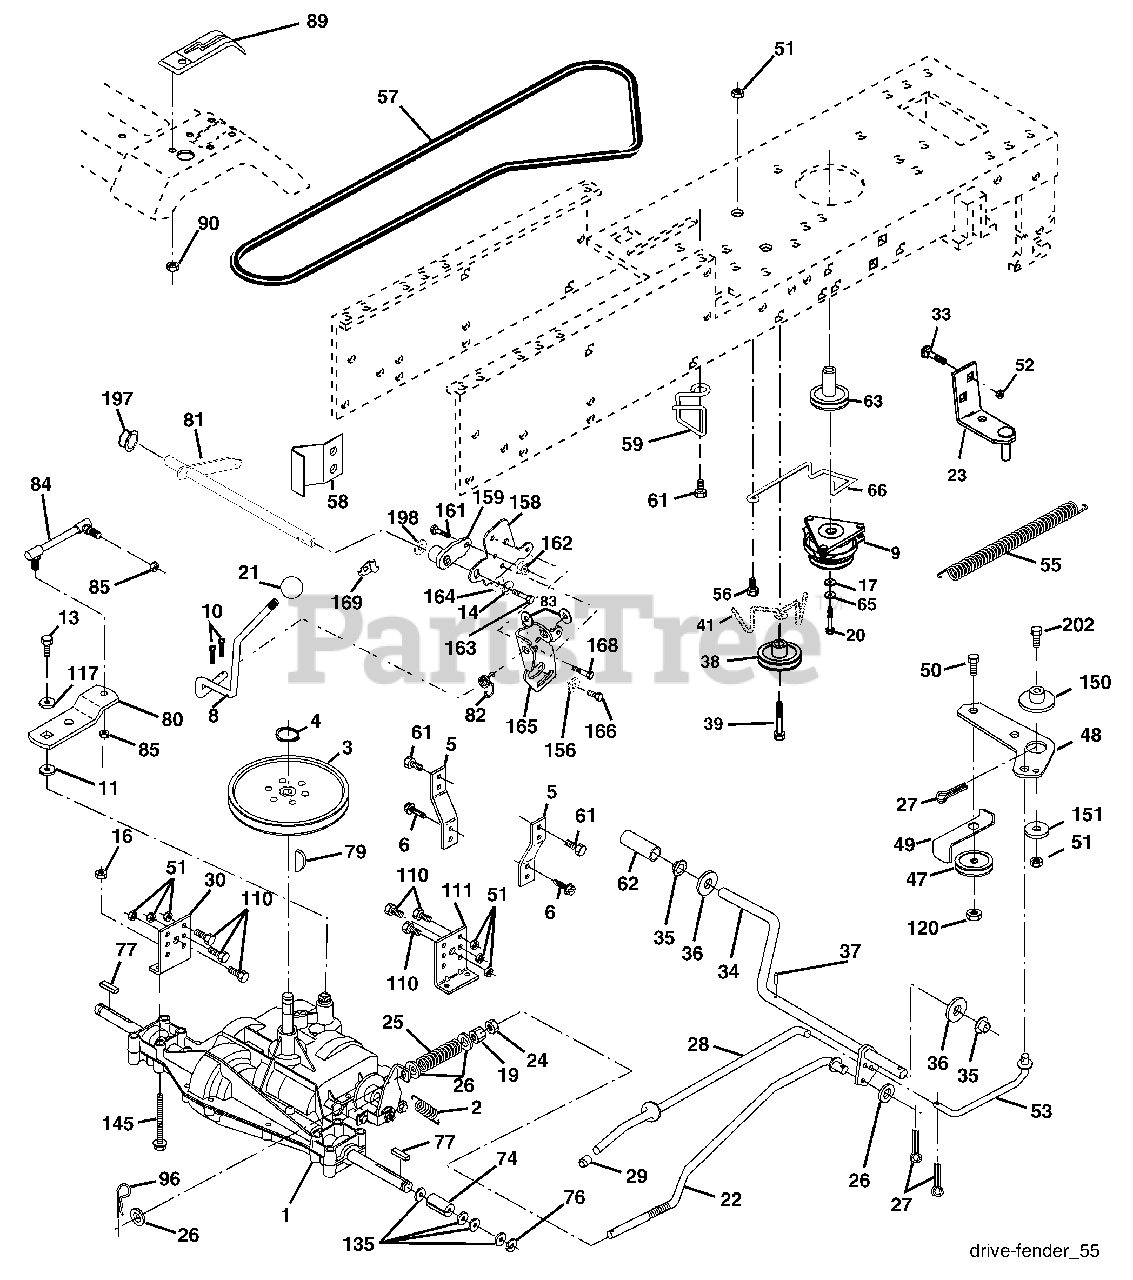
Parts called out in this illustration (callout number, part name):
2	Spring Brake Return
3	Pulley Transaxle
4	Ring Retainer
5	Strap Torque
6	Screw 5/16-18 x 3/4
8	Rod Shift Fender Adjust Yt
9	Clutch Ogura
10	Pin, Cotter 1/8 x 1
11	Washer Plate
13	Bolt 1/4-28
14	Washer Lock Hvy Helical
16	Nut Lock Hx w/Ins. 5/16-18 Unc
17	Washer 1-1/2 x 15/32 x .250
19	Nut, Lock Hex w/Ins. 3/8-16 Unc
20	Bolt 7/16-20 x 4 Gr. 5-1.5
21	Knob
23	Bracket Anti Rotation
24	Nut, Hex Jam 3/8-16
25	Spring, Rod, Brake
26	Washer 13/32 x 5/8 x 16 Ga.
27	Pin, Cotter 1/8 x 3/4
28	Rod, Brake, Park
29	Cap, Brake Parking Black
30	Bracket, Transaxle, L.H.
33	Bolt 3/8-16 x 1
34	Shaft, Foot Pedal
35	Bearing Nylon
36	Washer 21/32 x 1 x 16 Gauge
37	Pin,Roll 3/16 x 1
38	Pulley Idler Composite
39	Bolt Rdhd 3/8-16 Unc x 3
41	Keeper, Idler
47	Pulley, Idler
48	Bellcrank Clutch Grnd Drv Stl
49	Retainer, Belt
50	Bolt 3/8-16 x 1-1/2
51	Nut, Crownlock 3/8-16
52	Nut
53	Link, Clutch
55	Spring, Return, Clutch
56	Screw 3/8-16 x 1-1/4
57	V-Belt, Drive
58	Keeper, Belt, Transaxle, R.H.
59	Keeper Belt Centerspan
61	Screw 3/8-16 x .875
62	Cover, Foot Pedal
63	Pulley, Engine
65	Washer, Lock Hvy Hlcl Spr 7/16
66	Keeper Belt Engine F-proof
74	Spacer Split 1.032 x .750
76	E-Ring
77	Key Square 1/4 x 2
79	Key Woodruff #9 3/16 x 3/4
80	Arm Shift
81	Shaft Asm Cross Tapered
82	Spring, Torsion
83	Washer 17/32 x 3/4 x 16 Gauge
84	Link Transaxle
85	Nut Lock Center 1/4-28
90	Screw Hex Wsh Hi-Lo 1/4-1/2 Unc
96	Retainer Spring 1" Zinc/cad.
110	Bolt Hex 3/8-16 x 3/4 Gr. 5
111	Bracket, Transaxle, R.H.
117	Washer 9/32 x 3/4 x 16
120	Nut Lock Flg. 3/8-16 Unc
145	Bolt Hex Flghd 5/16-18 Gr. 5
150	Spacer
151	Washer 13/32 x 2 x 10 Ga.
156	Washer Srrted 5/16ID x 1.125
158	Bracket Shift Mount
159	Hub Shift
161	Bolt Rdhd Sqnk 1/4-20 x 3/4 Gr 5
162	Nut Crownlock 1/4-20 Unc
163	Bolt Hex Fin 1/4-20 Unc x 1 Gr 5
164	Washer 5/8 x .281 x 10 Ga
165	Bracket Pivot Lever
166	Screw 5/16-18 x 5/8
168	Bolt Shoulder 5/16-18 x .561
169	Plate Fastening Lt
197	Nyliner Snap-In 5/8" Id
198	Washer Nyl 7/8 Id x .105
